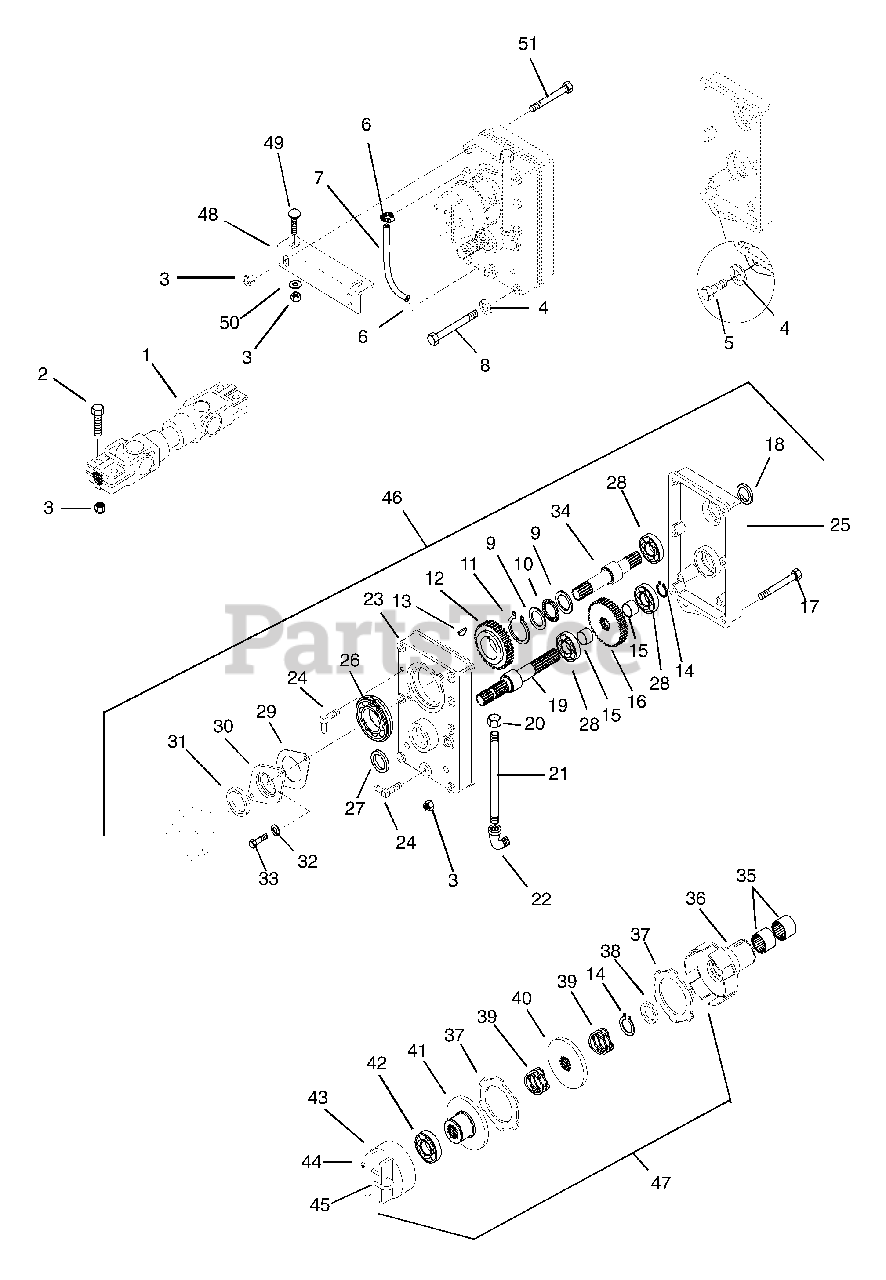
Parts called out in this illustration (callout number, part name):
1	Assembly, PTO U-Joint
2	Bolt-Hex .38-16 x 1.75 Grade 5
3	Nut-Locking-Center .38-16
4	Washer-Locking .50 X 1.25
5	Bolt-Hex .50-13 x 1.50 Grade 5
6	Hose Clamp
7	Hose, 1/4 Inch Viny
8	Bolt-Hex .50-13 x 4.25 Grade 5
9	Washer-Thrust 1.55
10	Bearing-Needle-Thrust 1.0 x 1.55 x .078
11	Ring-Retaining-External 1.819 x .062
12	Gear, PTO
13	Key-Woodruff .25 x 1
14	Ring-Retaining-External .906 x .078
15	Spacer 1.01 x 1.25 x .645
16	Gear, PTO
17	Bolt-Hex .38-16 x 3.50 Grade 5
18	Seal .984 x 1.6 x .25
19	Shaft, PTO
20	Cap, Pipe 3/8"
21	Nipple, Pipe .38 x 6.0
22	Elbow .38 x 90
23	Cover
24	Elbow, Hose
25	Case, PTO
26	Bearing-Ball 1.97 x 3.14 x .63
27	Seal 1.25 x 1.75 x .25
28	Bearing-Ball .984 x 2.047 x .591
29	Gasket, Front PTO Cap
30	Cap, Front PTO
31	Seal 2.250 x 3.002 x .375
32	Washer-Lock .31 x .078
33	Bolt-Hex .31-18 x .75 Grade 5
34	Shaft, PTO Input (Upper)
35	Bearing-Roller 1.0 x 1.312 x .75
36	Hub, PTO Clutch
37	Disc, Clutch
38	Seal 1.0 x 1.50 x .25
39	Spring-Wave
40	Plate, Clutch
41	Hub, Clutch Actuating
42	Bearing-Ball 1.57 x 3.15 x .71
43	Trunnion, Forward-Reverse Clutch
44	Pin-Cotter .062 x .75
45	Pin, Clutch Spring
46	PTO Assembly-PM 400
47	PTO Clutch Service Kit
48	Bracket, PTO
49	Bolt, Round Head Square Neck .38-16 x .75 Grade 5
50	Washer-Flat-Steel .406 x .812 x .065
51	Bolt-Hex .38-16 x 3.75 Grade 5
